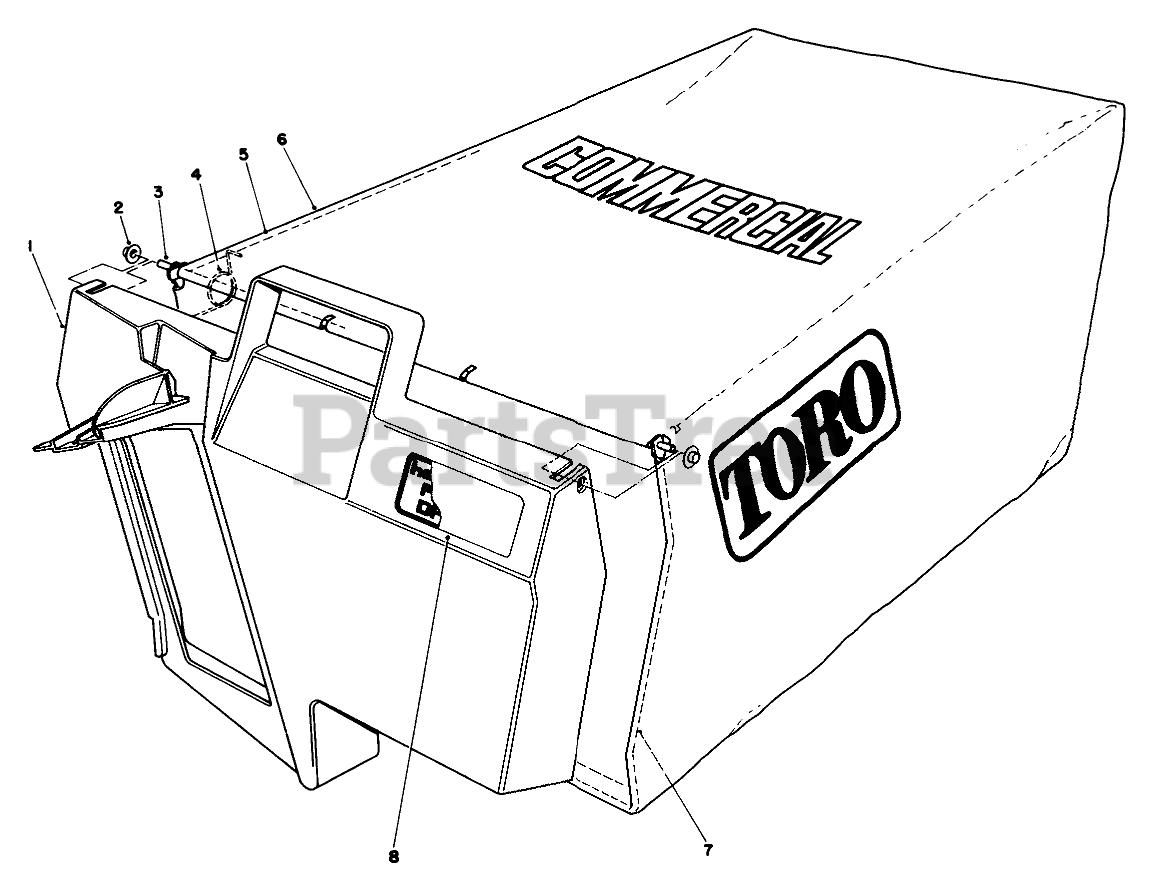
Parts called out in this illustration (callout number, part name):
1	DOOR-BAG, GRASS
2	NUT-PUSH
3	HINGE-DOOR, BAG
4	SPRING
5	FRAME-BAG, UPPER
6	Bag
7	FRAME-BAG
8	BAG DOOR DECAL
